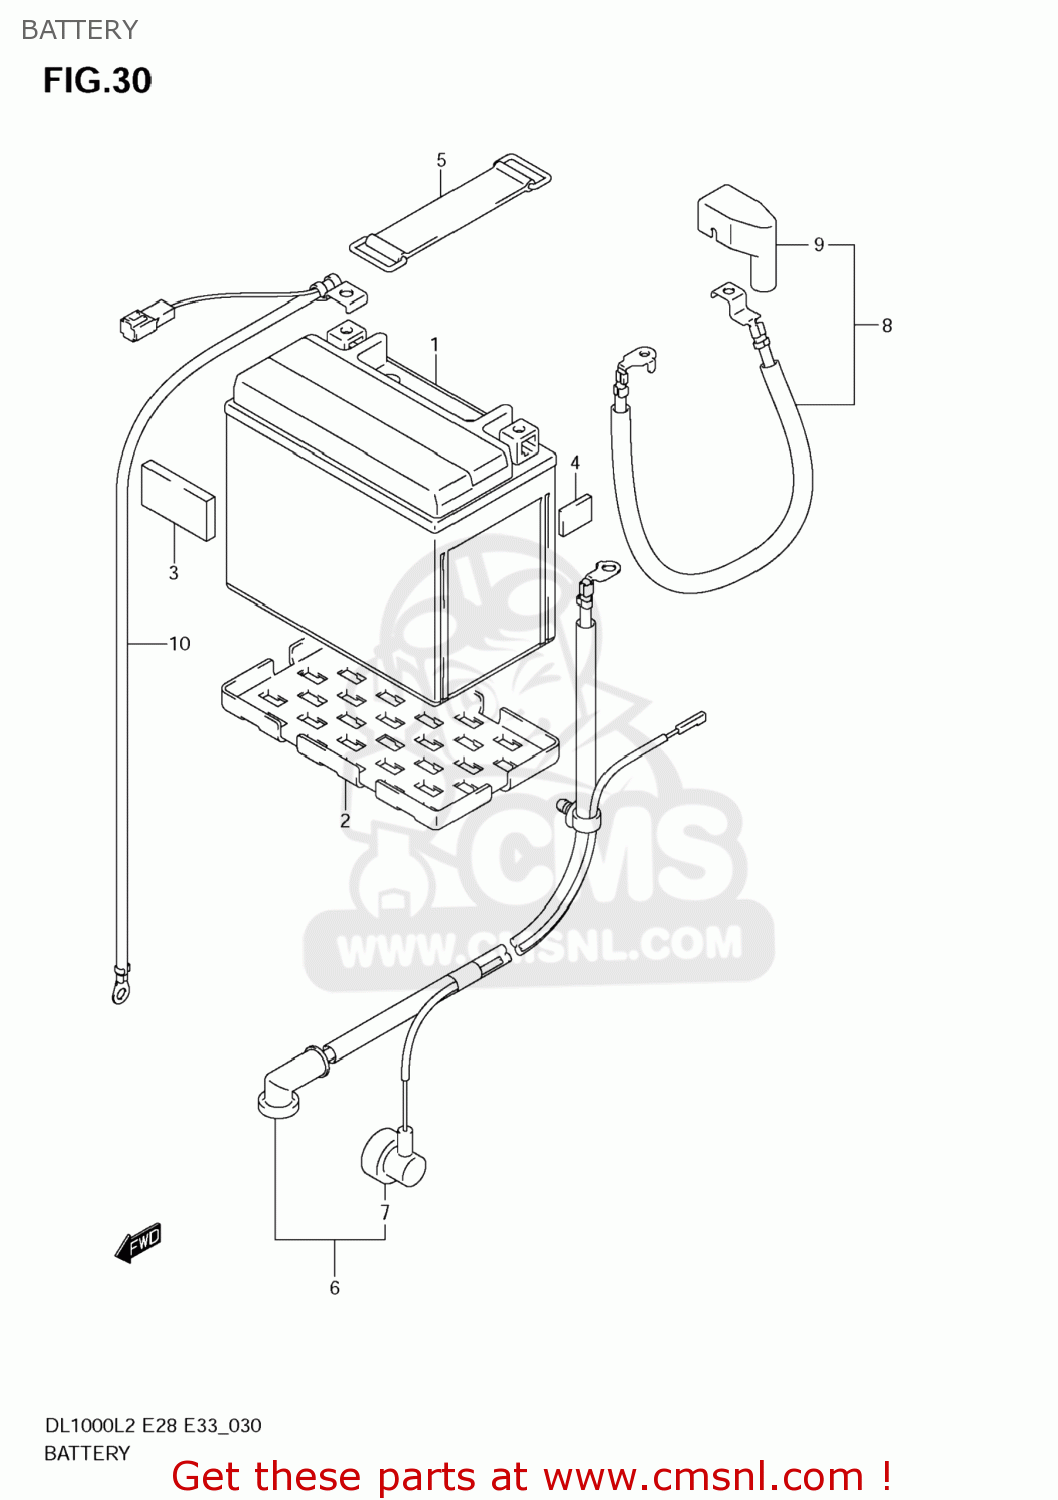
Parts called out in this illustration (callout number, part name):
1	BATTERY ASSY (12V) YTX14-BS
2	PROTECTOR,BATTERY
3	PROTECTOR,BATTERY(70X100X6)
4	CUSHION,FUEL TANK NO.2
5	BAND
6	WIRE,STARTER MOTOR LEAD
7	CAP,OIL PRESSURE SWITCH
8	WIRE,BATTERY PLUS LEAD
9	CAP,BATTERY PLUS LEAD
10	WIRE,BATTERY MINUS LEAD
